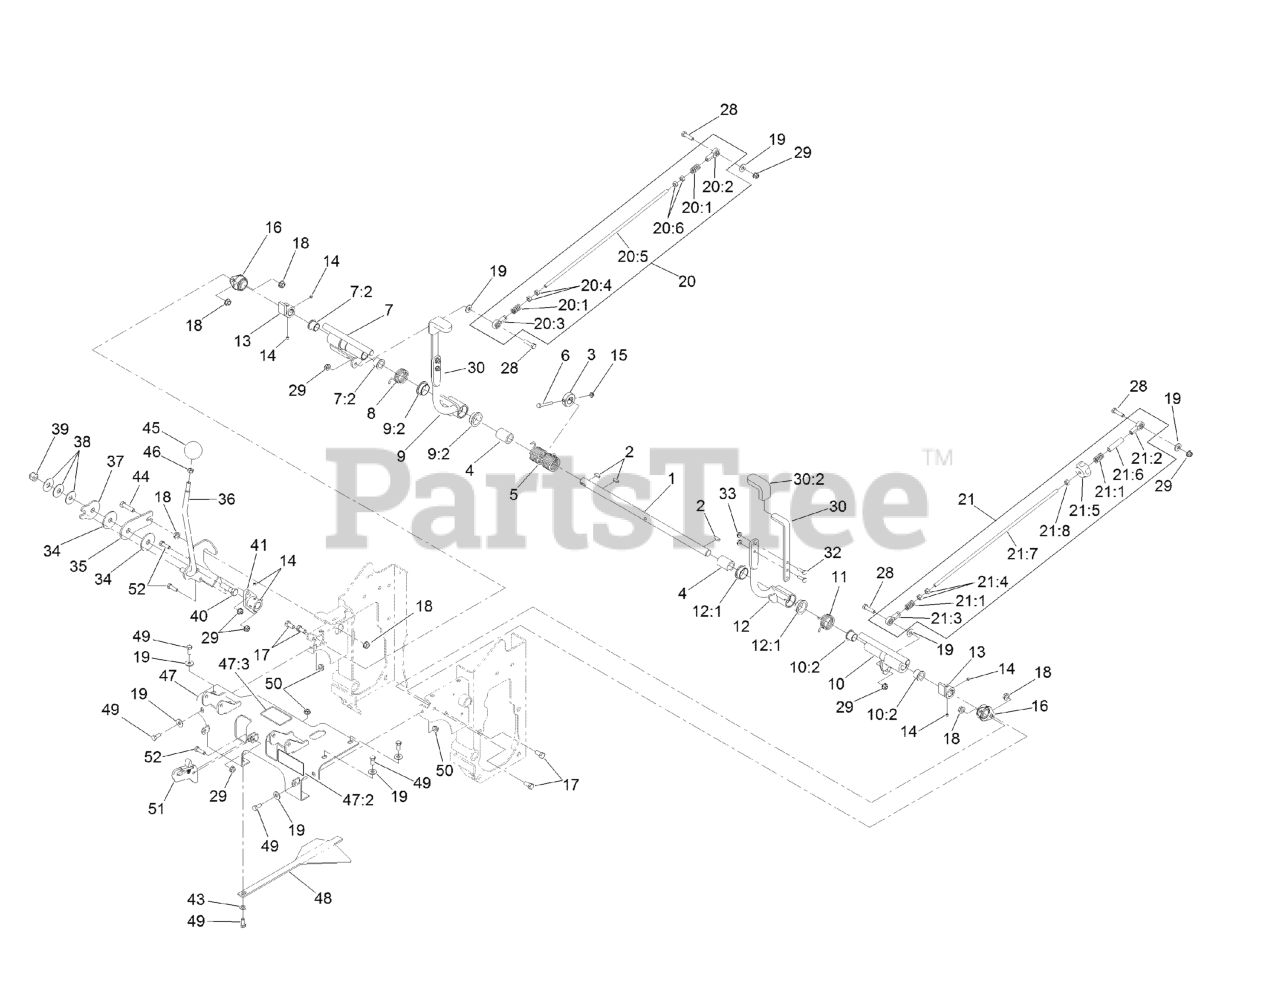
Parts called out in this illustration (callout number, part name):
1	SHAFT-CONTROL, SPEED
2	KEY-WOODRUFF
3	STOP-HUB, CENTER
4	BUSHING-PLASTIC
5	SPRING-TORSION, DOUBLE
6	SCREW-HH
7	RH CONTROL HUB ASM
7:2	BEARING-FLANGE, IGLIDE
8	SPRING-TORSION, RH
9	RH STEERING HANDLE ASM
9:2	BEARING-FLANGE, IGLIDE
10	LH CONTROL HUB ASM
10:2	BEARING-FLANGE, IGLIDE
11	SPRING-TORSION, LH
12	LH STEERING HANDLE ASM
12:1	BEARING-FLANGE, IGLIDE
13	HUB-SPEED CONTROL
14	SCREW-SET
15	NUT-LOCK, NI
16	BEARING-FLANGE, SIDE
17	SCREW-HH
18	NUT-HHF, WHIZ
19	WASHER-FLAT
20	RH PUMP LINKAGE ASM
20:1	SPRING-COMPRESSION
20:2	BALLJOINT-RH
20:3	BALLJOINT-LH
20:5	ROD-LINKAGE, STEERING
20:6	NUT-HEX
21	LH PUMP LINKAGE ASM
21:1	SPRING-COMPRESSION
21:2	BALLJOINT-RH
21:3	BALLJOINT-LH
21:5	KNOB-TRACKING
21:7	ROD-LINKAGE, STEERING
21:8	NUT-HEX
28	SCREW-HH
29	NUT-HF, NI
30	HANDLE ASM
30:2	GRIP-HANDLE, STEERING
32	SCREW-HH
34	DISC-FRICTION
35	PLATE-FRICTION, SPEED CON
36	LEVER-SPEED CONTROL
37	PLATE-FRICTION, SPEED CON
38	WASHER-DISC, SPRING
39	NUT-HEX
40	SCREW-HH
41	HUB-CONTROL, SPEED
43	WASHER-PLAIN
44	SCREW-HH
45	KNOB-BALL, SPEED CONTROL
46	NUT-JAM
47	CONSOLE ASM
47:2	DECAL-DANGER, DRIVELINE
47:3	Decal-Motor, Wheel
48	GUIDE-PLENUM
49	SCREW-HH
52	SCREW-HH
